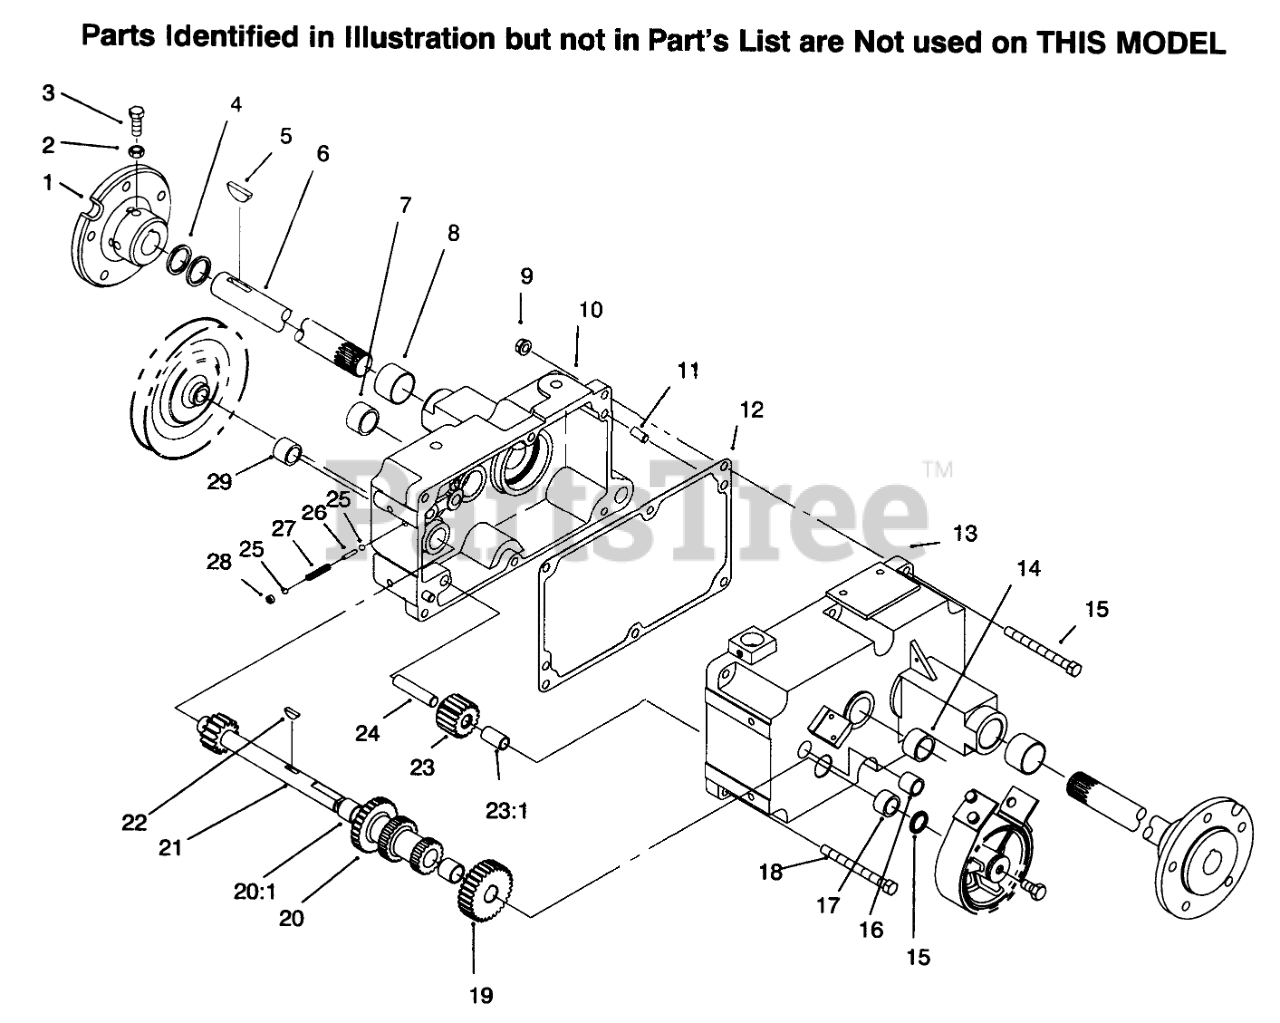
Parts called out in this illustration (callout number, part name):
1	Hub Rear
2	NUT-JAM
3	SCREW-SET, SQH
4	SEAL-OIL
5	KEY-WOODRUFF
6	AXLE-REAR
7	BEARING-NEEDLE
8	BEARING
9	NUT-LOCK, NI
10	Case Trans RH
11	PIN-DOWEL
12	GASKET-TRANSMISSION
13	Case Trans LH
14	SCREW-HH
15	SEAL-OIL
16	BEARING-NEEDLE
17	BEARING-NEEDLE
18	SCREW-HH
19	GEAR-CLUSTER SHAFT
20	GEAR-CLUSTER
20:1	BUSHING-BRONZE
21	SHAFT-CLUSTER
23	GEAR/BUSHING ASM-REVERSE IDLER
24	PIN-DIFFERENTIAL
25:1	Shift Lever
25:2	Shaft-Lever
26	PIN-SHIFT
28	CUP-PLUG
29	BEARING-NEEDLE
58	WASHER-THR
